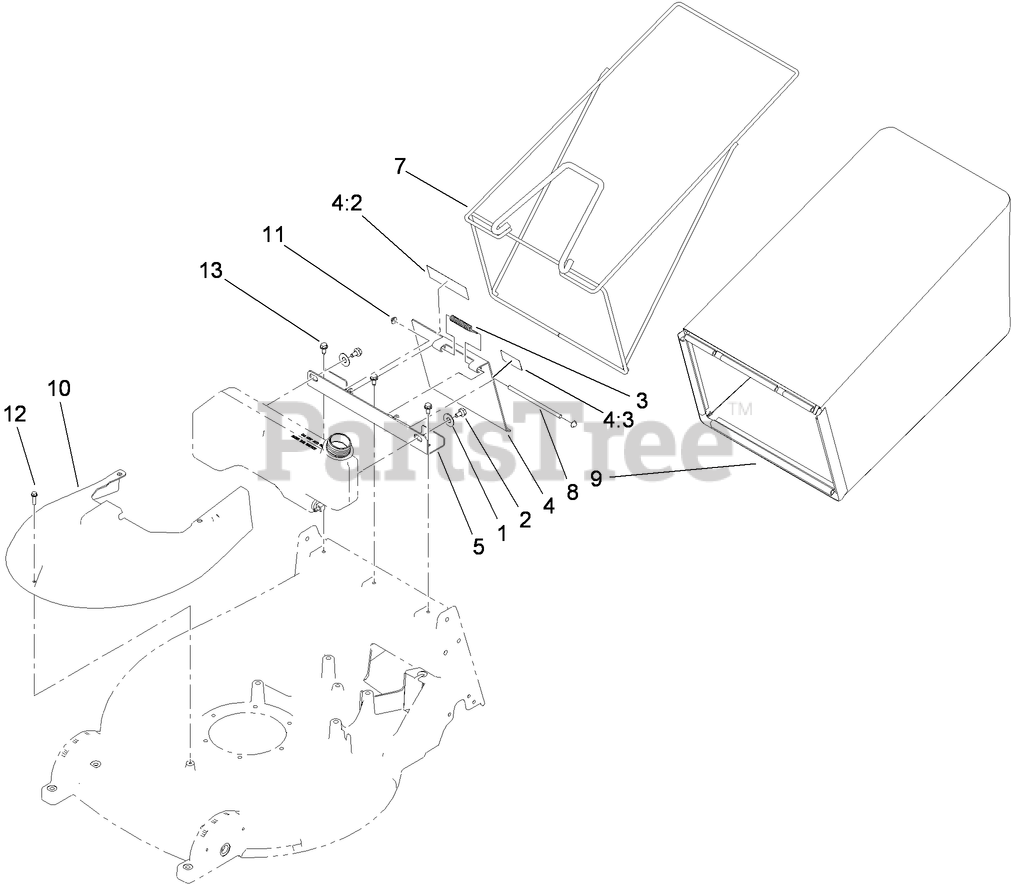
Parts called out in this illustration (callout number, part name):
1	WASHER-PLASTIC
2	BOLT-SHOULDER
3	SPRING-TORSION
4	DOOR ASM
4:2	DECAL-DANGER
4:3	Decal-Grease
5	BRACKET-MOUNT, BAG/DOOR
7	FRAME-BAG
8	ROD-PIVOT, DOOR
9	GRASS BAG ASM
10	COVER-SPINDLE
11	NUT-PUSH
12	SCREW-HWHTF
13	SCREW-HWHTF
